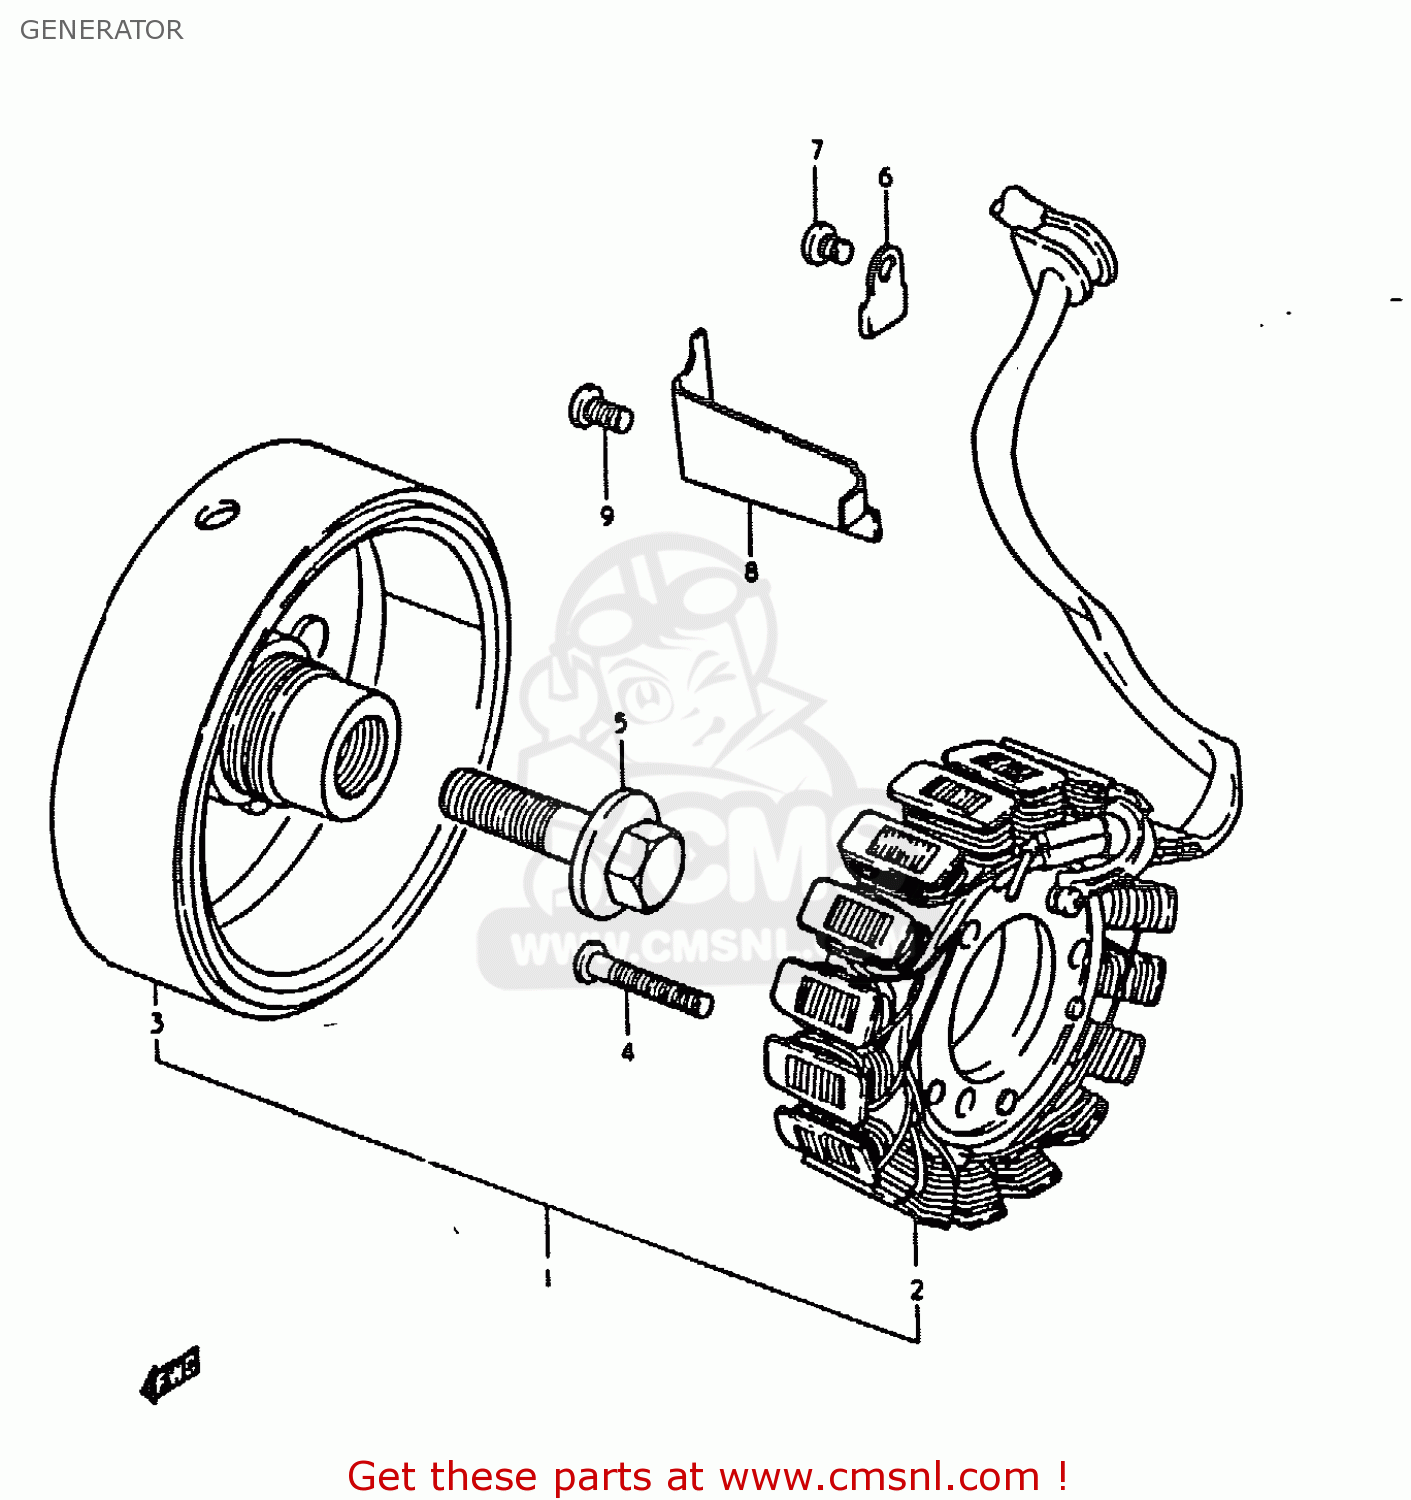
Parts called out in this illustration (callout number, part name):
1	GENERATOR ASSEMBLY
2	STARTER ASSY
3	ROTOR ASSEMBLY
4	SCREW
5	BOLT
6	CLAMP,GENERATOR LEAD WIRE
7	SCREW
8	CLAMP,GENERATOR LEAD WIRE
9	SCREW
